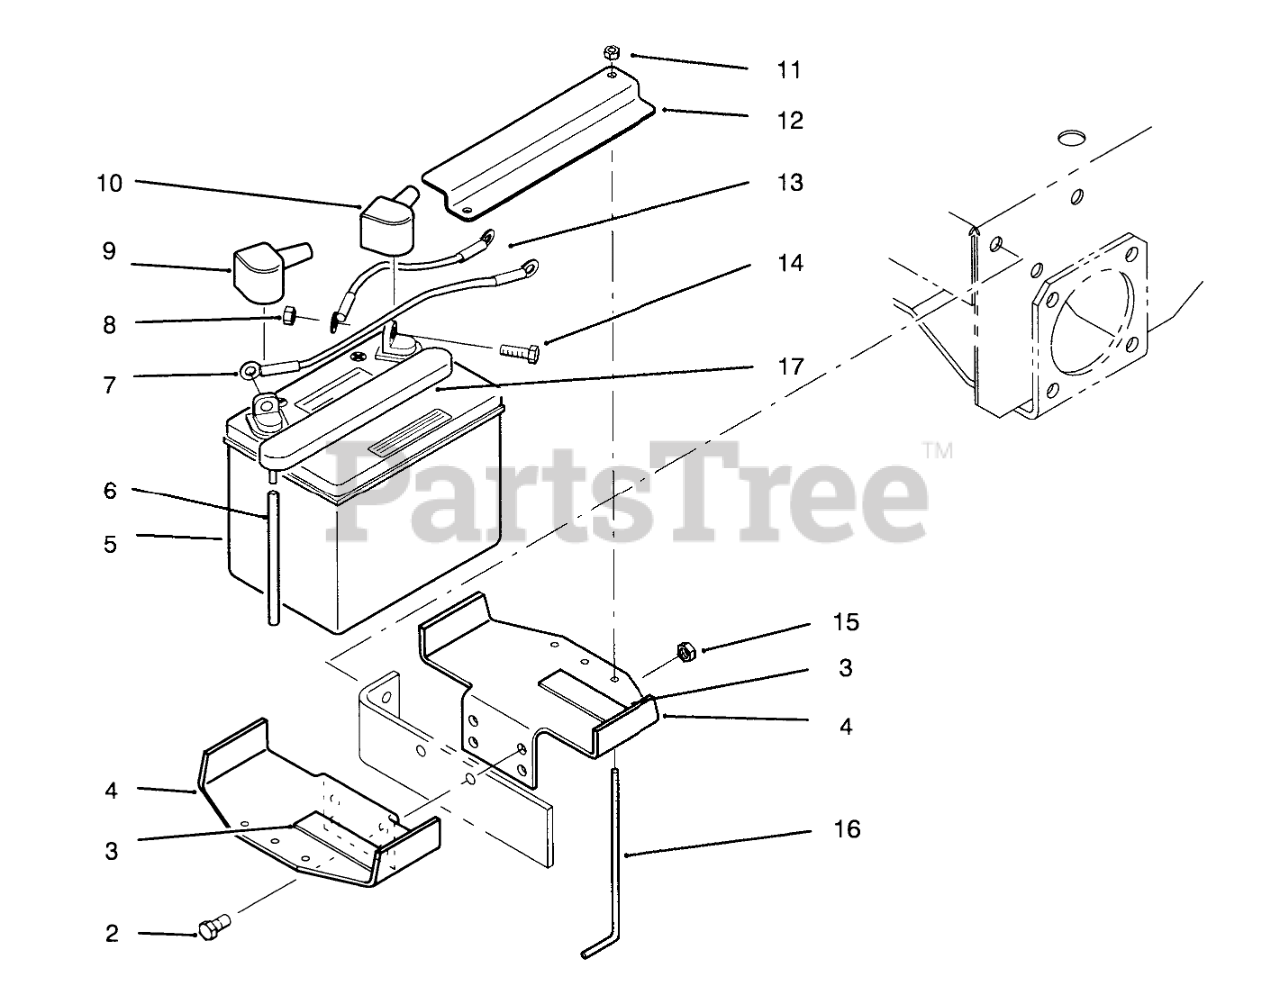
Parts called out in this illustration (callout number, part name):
2	SCREW-HH
3	PAD-TANK, FUEL
4	Battery
5	Battery
6	TUBE-VENT
7	WIRE ASM
8	NUT-KEPS
9	BOOT-TERMINAL, BLACK
10	BOOT-TERMINAL, RED
11	NUT-LOCK, NI
12	Clamp-Battery
13	WIRE ASM
14	SCREW-HH
15	NUT-LOCK, NI
16	ROD-SUPPORT, BATTERY
